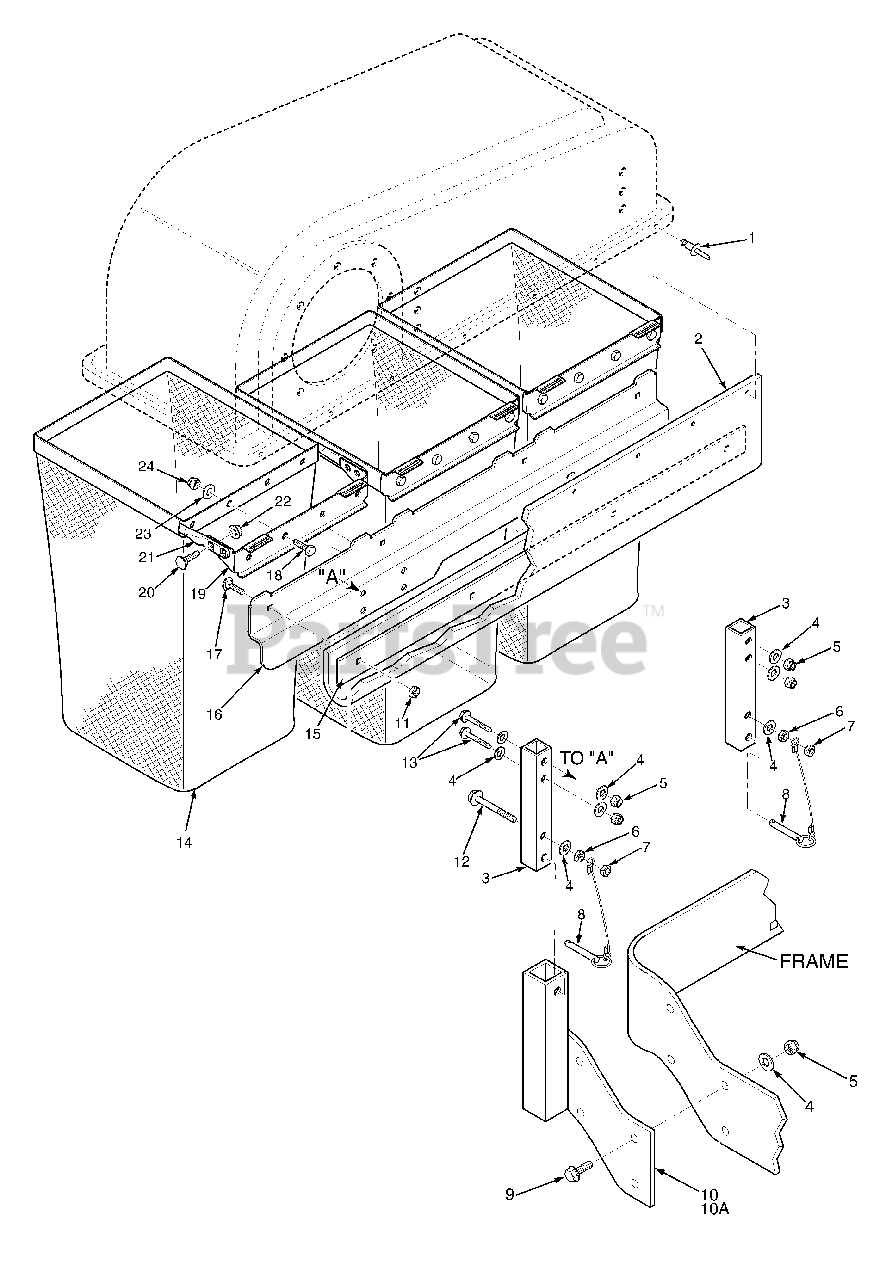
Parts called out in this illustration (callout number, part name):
1	Pop Rivet, 3/16 x .652
2	Seal, Hood
3	Tube, Upright
4	Flatwasher, 3/8-.391 x .938 x .105
5	Nut, Elastic Stop 3/8-16
6	Nut, 3/8-16
7	Hex Lock Nut, 3/8-16
8	Pin, Ring 1/2 x 2-1/4"
9	Bolt, Hex Head 3/8-16 x 1"
10	Mounting Bracket Weldment R.H
10A	Mounting Bracket Weldment L.H.
11	Lock Nut, 1/4-20 Center
12	Bolt, Hex Head 3/8-16 x 2-1/4"
13	Bolt, Hex Head 3/8-16 x 2-1/2"
14	Bag Assembly, GC-STC
15	Retainer, Seal
16	Support, Bag Frame
17	Bolt, Carr. 1/4-20 x 3/4"
18	Bolt, Hex Head 5/16-18 x 3/4"
19	Mount, Bag Frame Tube
20	Bolt, Carr. 5/16-18 x 3/4"
21	Tube, Bag Support
22	Nut, Serr. Flange 5/16-18
23	Flatwasher, 5/16-.375 x .875 x .083
24	Nut, Elastic Stop 5/16-18
